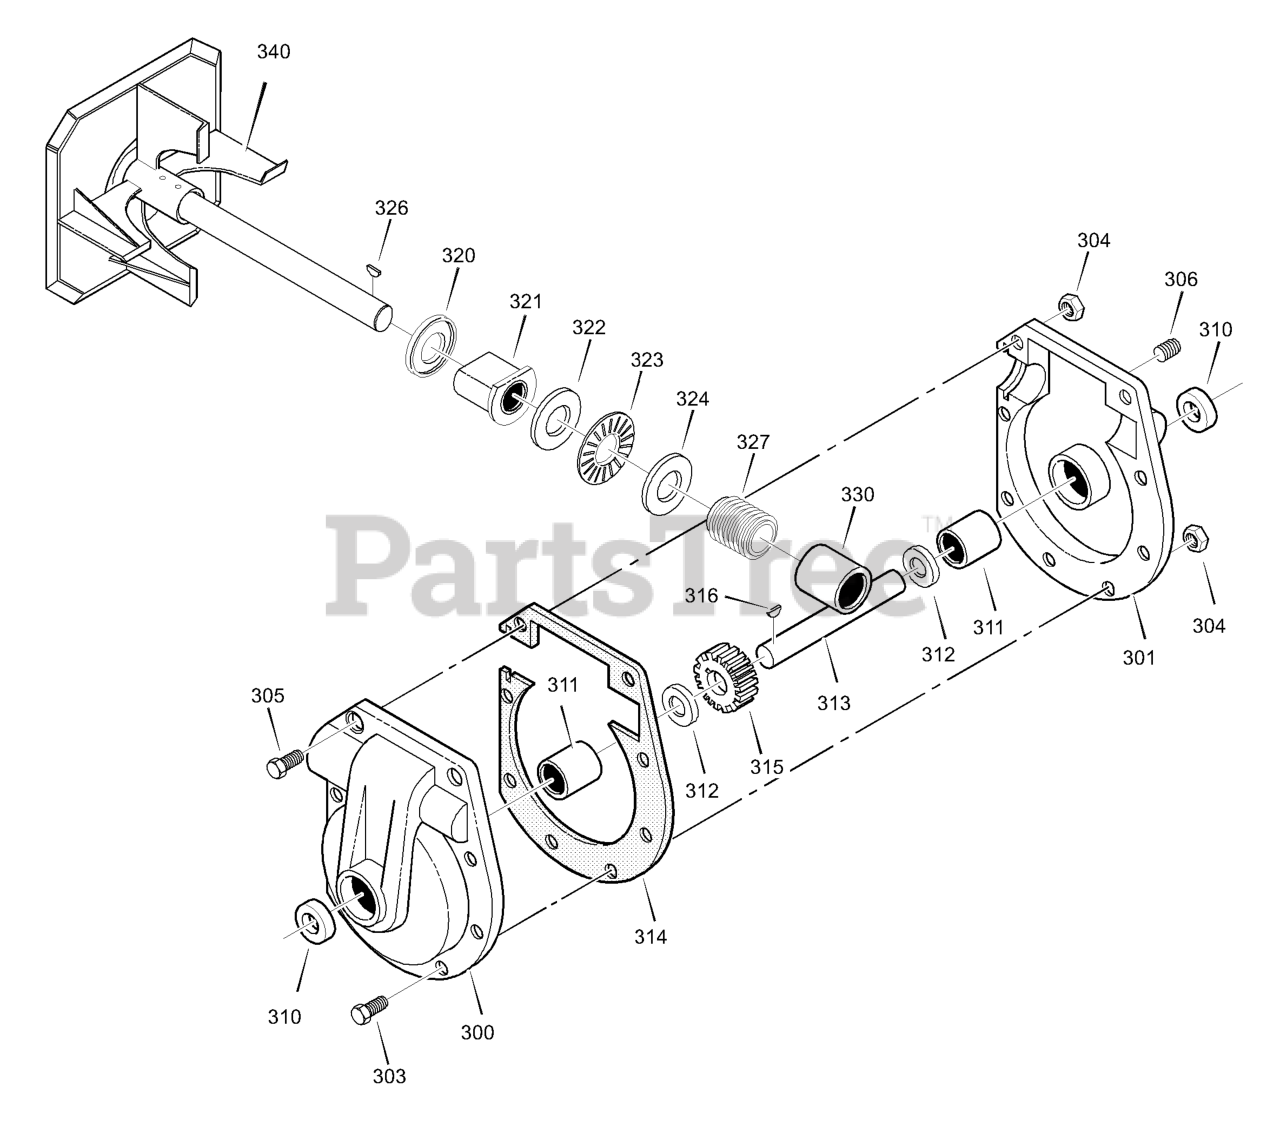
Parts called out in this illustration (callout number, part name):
300	CASE, GEAR, RH
301	CASE, GEAR, LH
303	SCREW, 5/16-24 x 1.00
304	NUT, 5/16-24
305	SCREW, 5/16-18 x 1.50
306	PLUG, PIPE 1/4-18
310	SEAL, OIL
311	BEARING, SLEEVE
312	WASHER, FLAT
313	SHAFT, AUGER OUTPUT
314	GASKET, GEAR BOX
315	GEAR
316	KEY, WOODRUFF #61
320	RING, QUAD.
321	BEARING, FL
323	BEARING, ROLLER
327	GEAR, WORM
340	IMPELLER
